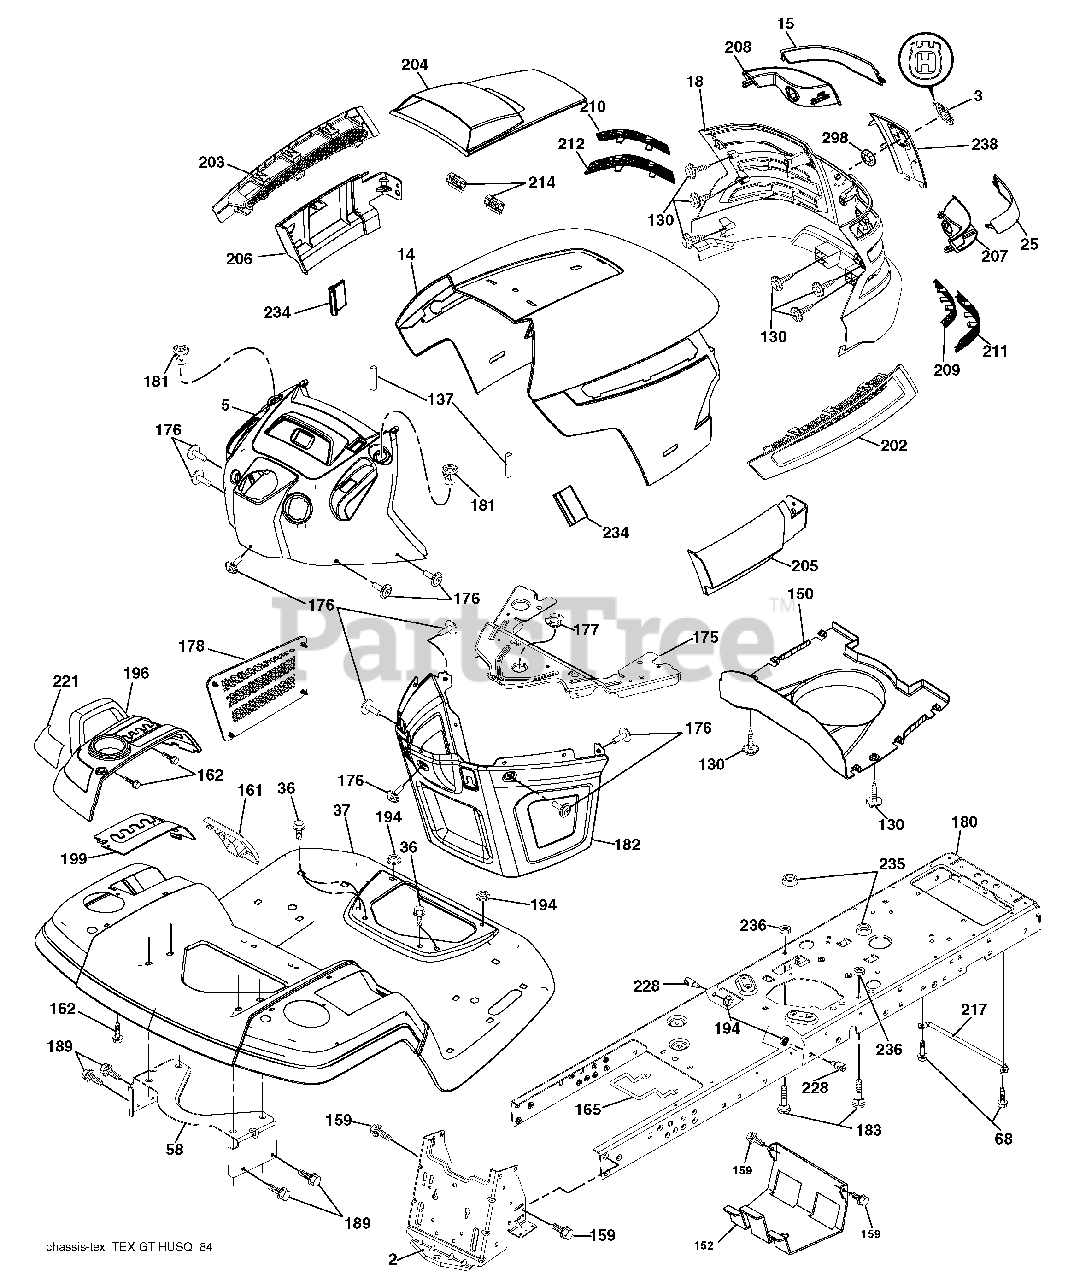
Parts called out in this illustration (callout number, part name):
2	Drawbar
3	Logo Husq.
14	Hood
18	Grille Asm
36	Screw 5/16-18 x 3/4
37	Fender
58	Bracket Fender
68	Screw 5/16-18 x 1/2
130	Screw #10 x 0.750 BOS Thread
137	Bumper Dash
150	Duct Heat Hood
152	Shield Browning/Debris
159	Screw 3/8-16 x 3/4
161	Console Fuel Window
162	Screw Hex Wsh Hi-Lo 1/4 x 1/2
165	Bracket Support Tank
175	Crossmember
176	Screw 10-24 x 5/8 Wshd Qdrx
177	Bushing Steering
178	Cargo Asm. Net
180	Chassis
181	Bushing Mtg. Fender Crgo.
182	Dash Lower
183	Bolt 5/16-18 x 1-1/4
189	Screw 5/16-18 x 3/4
194	Nut Lock Hex Flange 5/16-18
196	Console Asm. Deck Lift
199	Plate Deck Lift
202	Vent Side Hood RH
203	Vent Side Hood LH
204	Vent Asm Hood Top
205	Skirt Hood Side RH
206	Skirt Hood Side LH
209	Insert Hex Top RH
210	Insert Hex Top LH
211	Insert Hex Bottom RH
212	Insert Hex Bottom LH
214	Clip Retainer
221	Reflector LH
228	Stud Fastener
234	Bumper Hood
235	Spacer Fender
236	Nut Center Lock 5/16-18 unc
238	Trim Husq.
